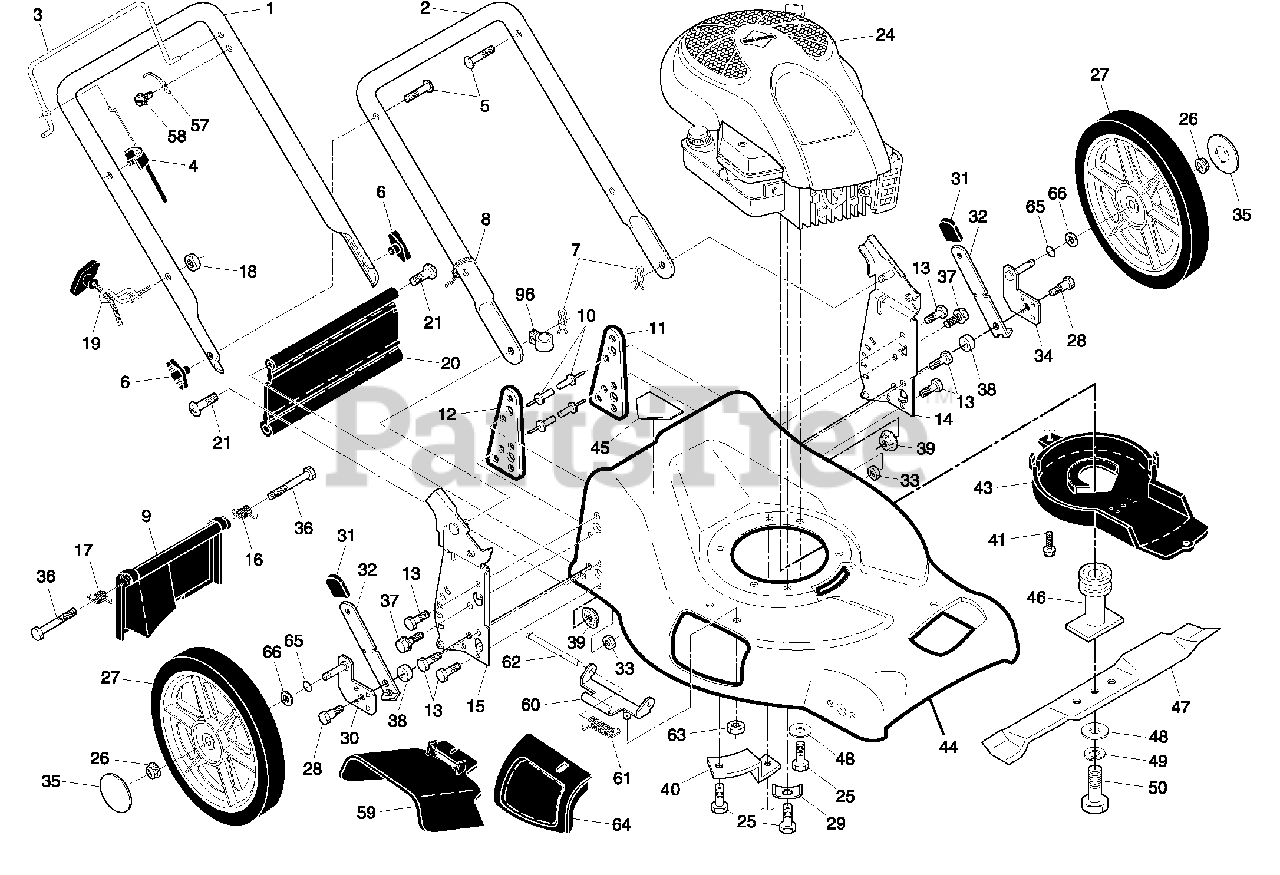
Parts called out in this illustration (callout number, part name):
1	Upper Handle
2	Lower Handle
3	Control Bar
4	Engine Zone Control Cable
5	Handle Bolt
6	Handle Knob
7	Hairpin Cotter
8	Wire Tie
9	Rear Door Assembly
10	Pop Rivet
11	Support Bracket, LH
12	Support Bracket, RH
13	Screw 1/4-20 x 5/8
14	Handle Bracket, LH
15	Handle Bracket, RH
16	Spring, Rear Door, LH
17	Spring, Rear Door, RH
18	Keps Locknut 1/4-20
19	Rope Guide
20	Rear Skirt
21	Hinge Screw 1/4-20 x 1-1/4
25	Screw, Hex Head, Threaded, Rolled 3/8-16 x 2
26	Nut, Hex, Flangelock 3/8-16
27	Wheel & Tire Assembly, Rear, 12"
28	Bolt, Shoulder 5/16-18
30	Axle Arm Assembly, Rear, RH
31	Selector Knob
32	Selector Spring
33	Nut, Hex, Nylock 5/16-18
34	Axle Arm Assembly, Rear, LH
35	Hubcap
36	Bolt, Rear Door
37	Thread Cutting Screw w/Sems 5/16-18 x 3/4
38	Washer, Flat .34 x 1.38
39	Nut, Hex
40	Mounting Bracket, Debris Shield
41	Screw, Debris Shield
43	Debris Shield
44	Kit, Housing
45	Danger Decal
46	Blade Adapter / Pulley
47	Blade, 21"
48	Hardened Washer
49	Helical Washer 3/8
50	Blade Bolt, Hex Head, Grade 8
57	Bracket, Upstop
58	Screw
59	Discharge Deflector
60	Hinge Bracket
61	Spring
62	Rod, Hinge
63	Nut, Hex
64	Mulcher Door
65	O-Ring
66	Washer, Flat 1/2
96	Clip, Cable
96	Operator's Manual, English
96	Operator's Manual, French
96	Repair Parts Manual
